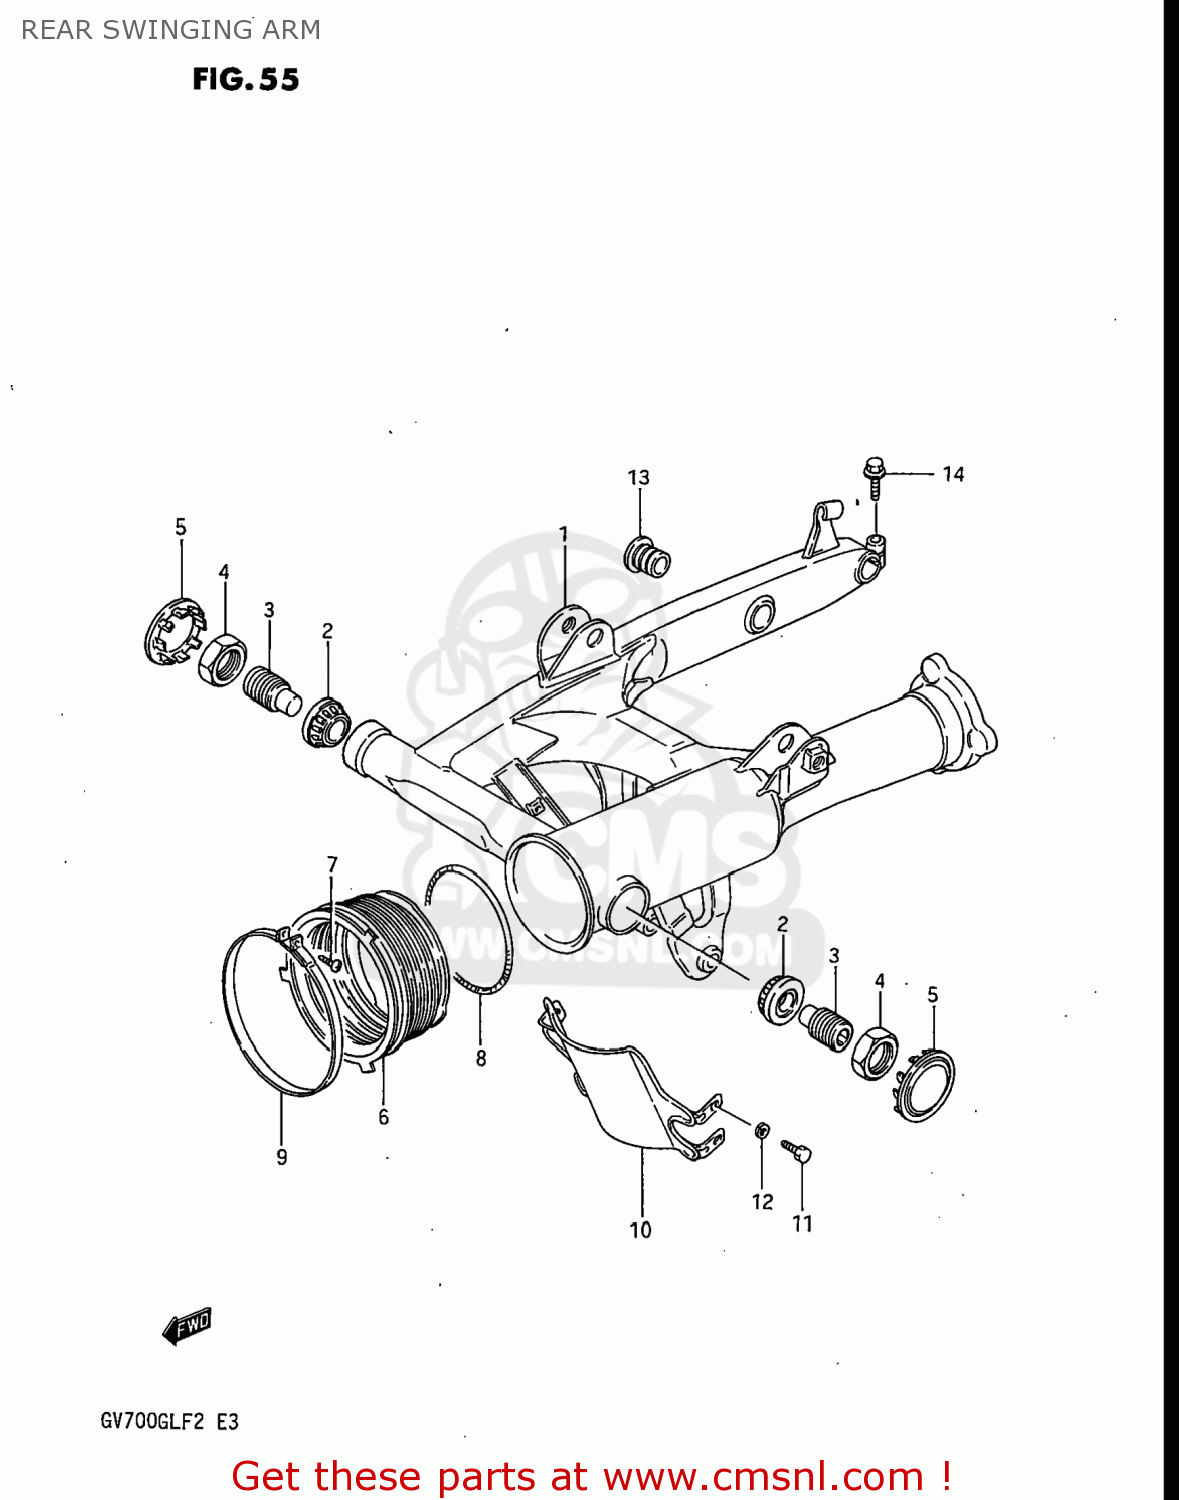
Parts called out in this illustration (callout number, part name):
2	BEARING(15X35X11.75)
3	BOLT,REAR SWING ARM PIVOT
4	NUT
5	CAP,RR SWINGING ARM PIVOT NUT
6	BOOT,PROPELLER SHAFT
7	SCREW 4X25
8	SPRING,PROPELLER SHAFT
9	CLAMP
11	BOLT
12	WASHER,LOCK
13	CAP(OD:26)
14	BOLT
